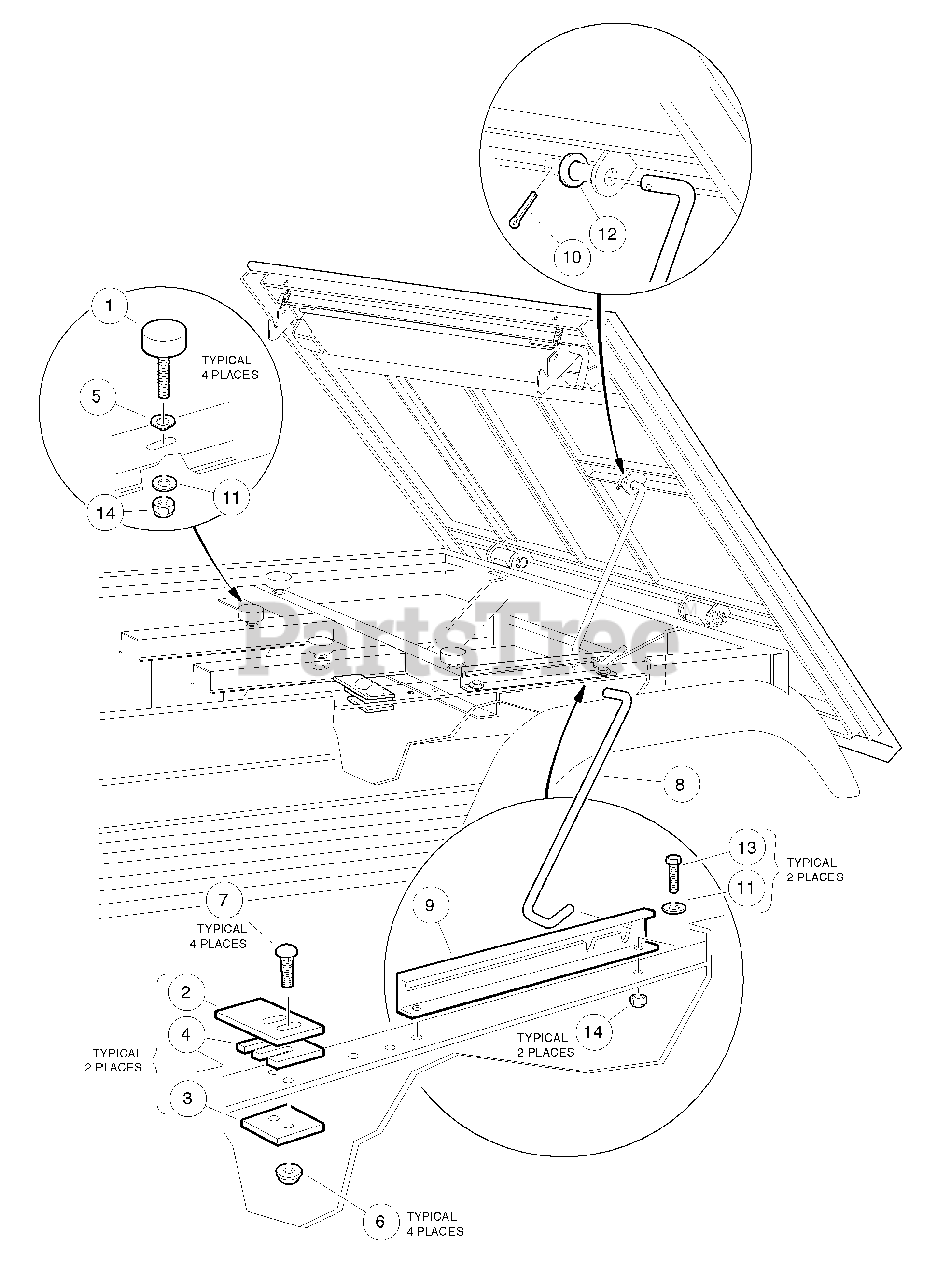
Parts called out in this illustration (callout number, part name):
1	Bumper, Rubber
2	Latch Plate, Tilt Bed
3	Plate, Latch Support
4	Latch Plate Shim
5	Washer, Wave
6	Locknut, 1/4-20 Hex Whiz
7	Bolt, Carriage, 1/4-20 X 1.0
9	Track, Prop Rod
10	Pin, 3/32 X 1.00 Sq Cut Cotter
11	Washer, 1/4 Type A Narrow Flat
12	Washer, 3/8 Type A Flat
13	Screw, 1/4-20 X 0.75 Hex-Head Cap
14	Locknut, 1/4-20 Nylon Insert
